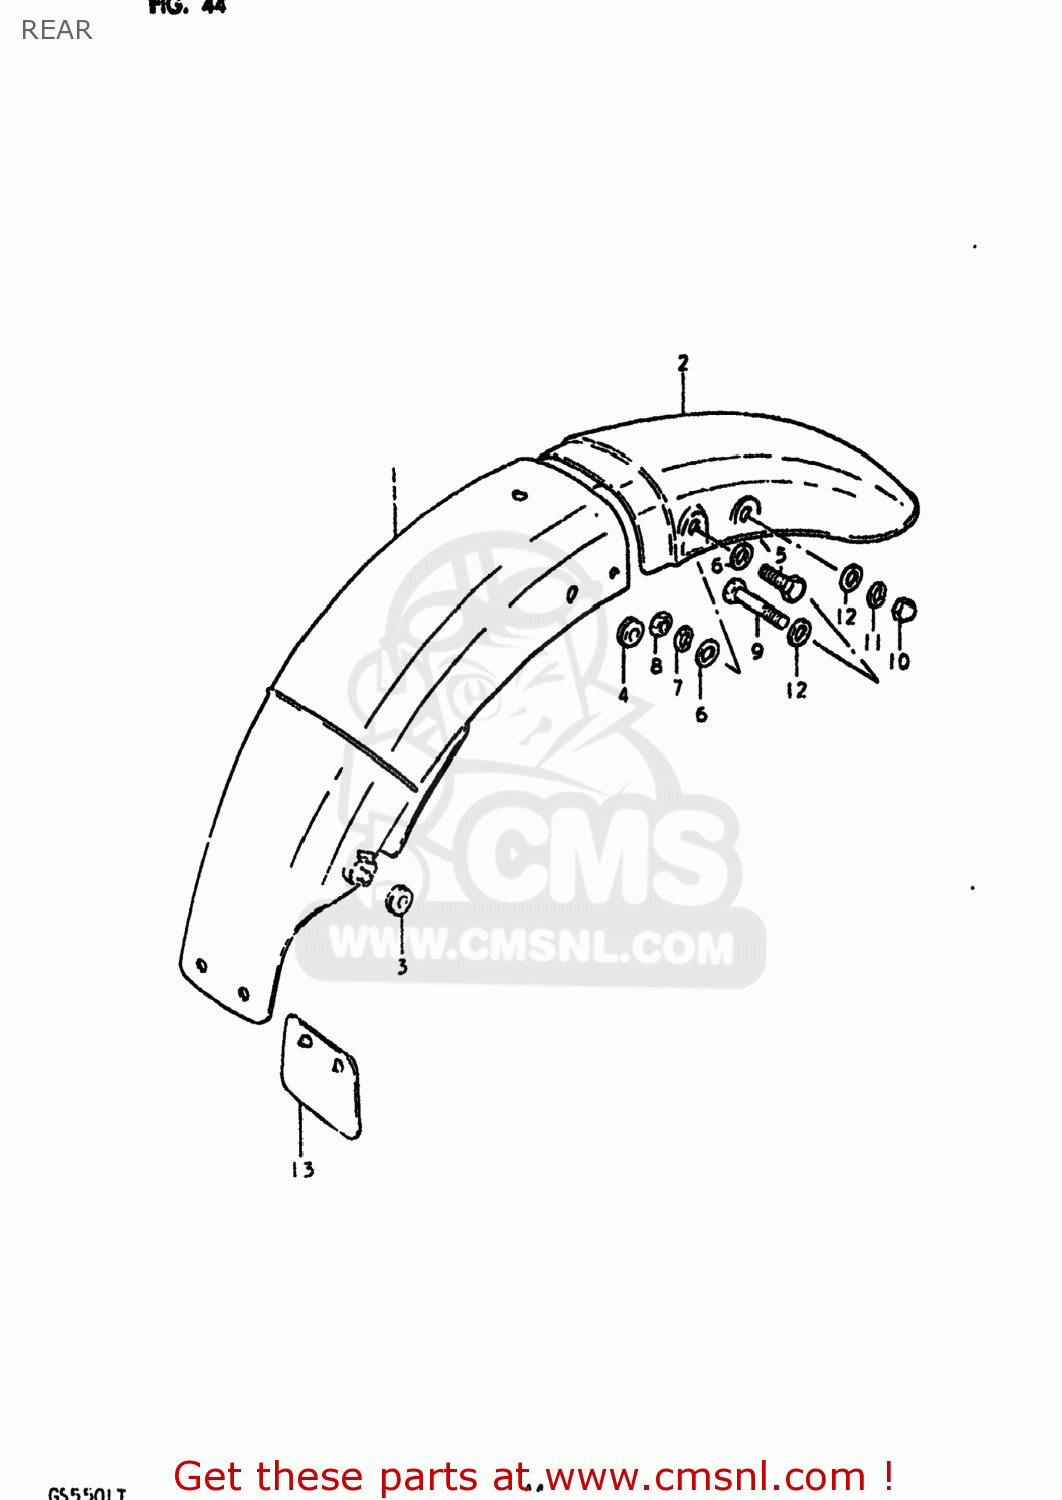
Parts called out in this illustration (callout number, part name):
1	WHEEL,REAR
2	BEARING
3	BEARING
4	SPACER(20.5X28X88)
5	RETAINER,REAR SPROCKET D
6	AXLE,REAR
7	SPACER,REAR AXLE
8	SPACER (17X33X21.1)
9	NUT
10	PIN,COTTER
11	WASHER (17X30X3.2)
12	DRUM,REAR SPROCKET MOUNT
13	BEARING
14	SEAL,OIL(33X62X7)
15	ABSORBER,REAR HUB SHOCK
16	BRACKET,RR,CALIPER
17	ADJUSTER,CHAIN
18	BOLT 8X50
19	NUT
20	SUPPORTER,CHAIN ADJUST
21	BOLT
22	DISC,BRAKE
23	BOLT(8X30)
24	WASHER
25	SPROCKET,REAR (NT:51)
26	BOLT
27	NUT
28	WASHER
29	TIRE 4.50H17
30	TUBE ASSEMBLY,WHEEL,INNER
31	BALANCER,WHEEL
32	BALANCER,WHEEL
